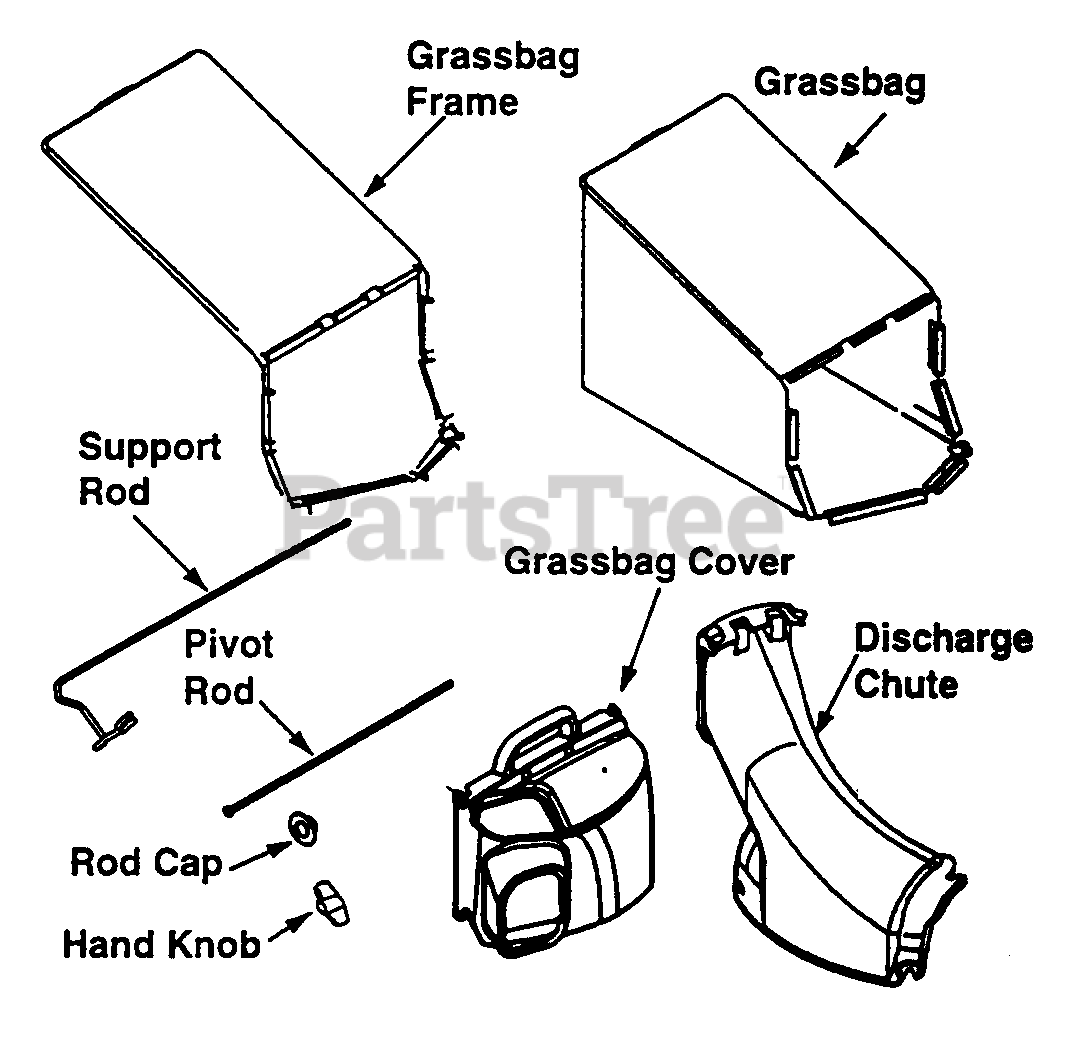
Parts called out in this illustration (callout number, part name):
1	Top Discharge Chute
2	Grassbag
5	Grassbag Cover
